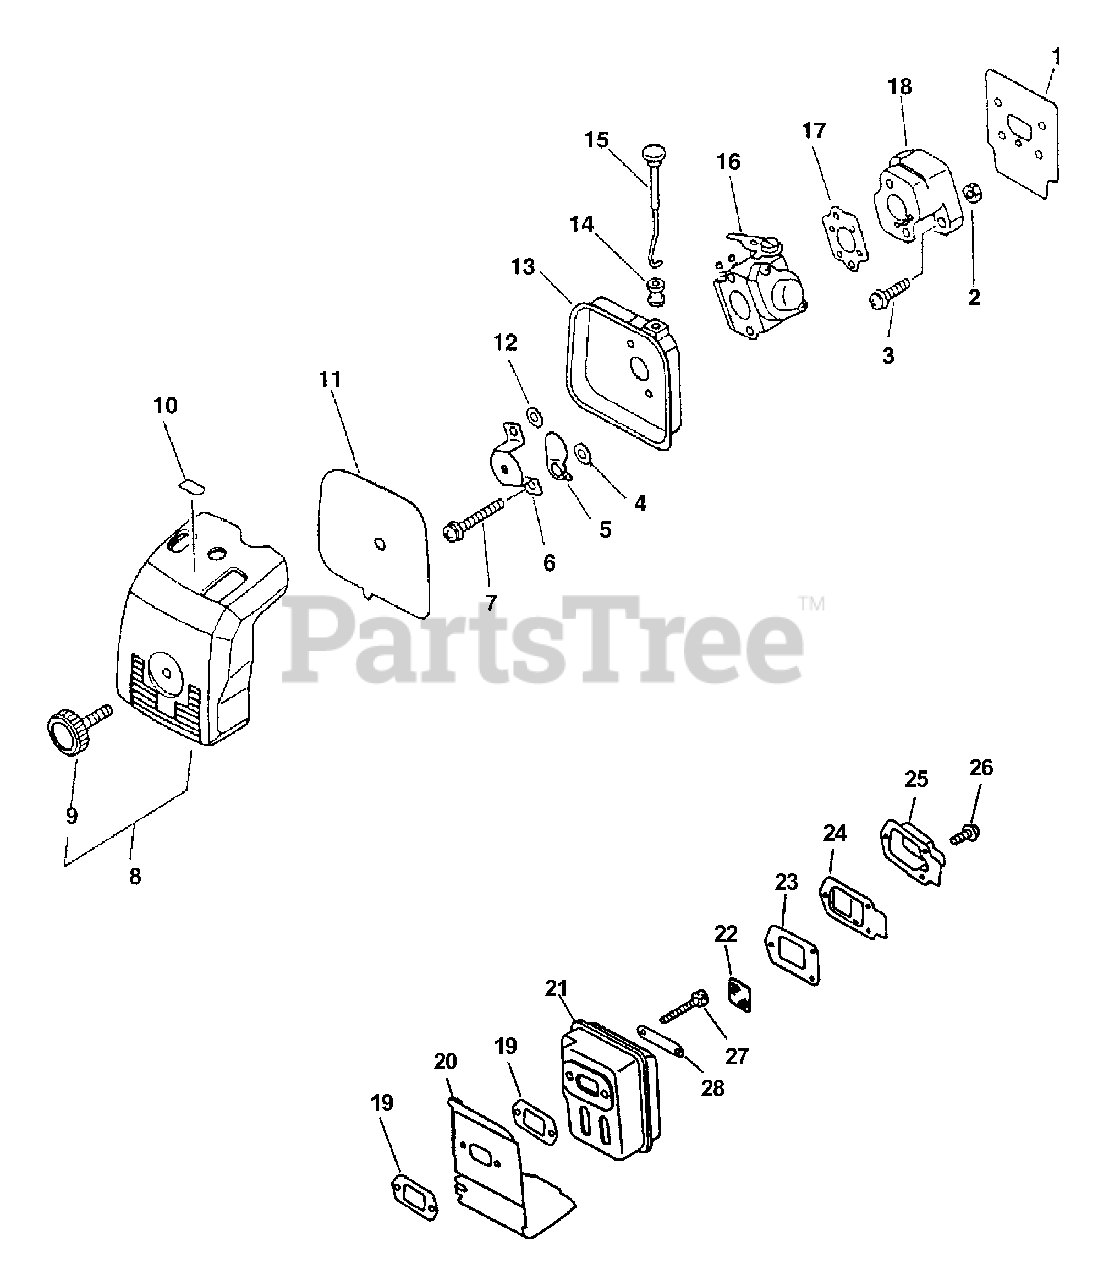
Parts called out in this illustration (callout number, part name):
1	SHIELD, INTAKE
3	SCREW - 5X20
4	WASHER - 5
5	SHUTTER, CHOKE
6	PLATE, PREVENT
7	SCREW - 5X57
8	AIR FILTER COVER ASSY
9	THUMBSCREW
10	LABEL - CHOKE
11	FILTER, AIR - HEAVY DUTY
12	WASHER - 5
13	CASE, AIR FILTER
15	ROD, CHOKE
16	CARBURETOR WT-424C
17	GASKET, INTAKE
18	INSULATOR, INTAKE
19	GASKET, EXHAUST
20	COVER, MUFFLER
22	SCREEN, SPARK ARRESTOR
23	GASKET, EXHAUST
24	GASKET, EXHAUST - INNER
25	GUIDE, EXHAUST - OUTER
26	SCREW - 4X10
27	SCREW - 5X55
